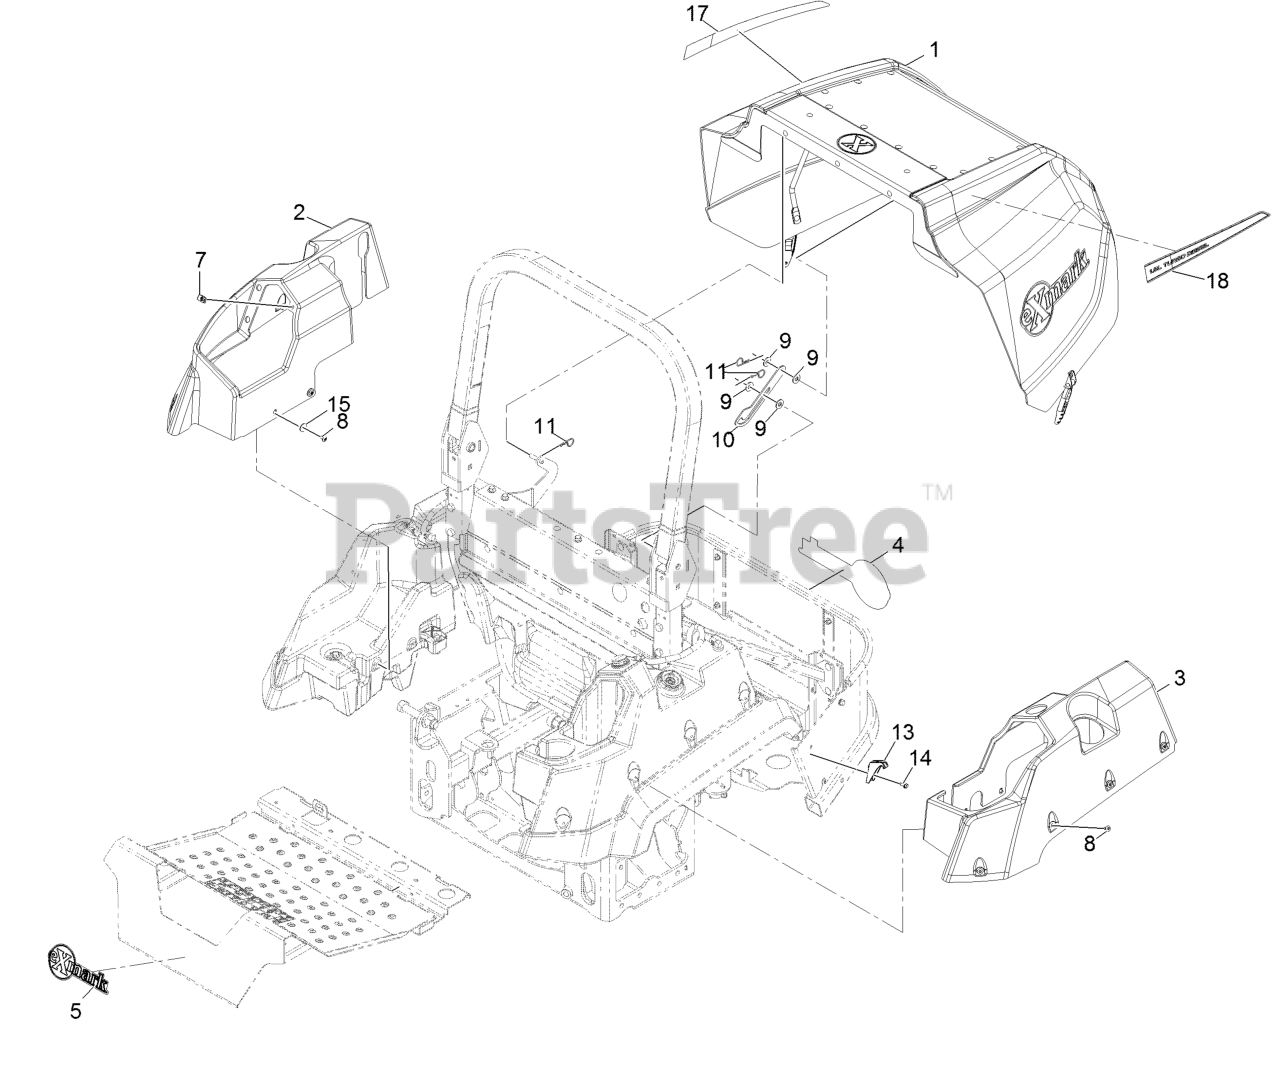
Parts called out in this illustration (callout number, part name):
1	Hood ASM
2	Cover-Tank, RH
3	Cover-Tank, LH
4	Decal-Exmark
5	Decal-Exmark
8	Screw-Torx
9	Washer-Flat
10	Prop-Hood
11	Pin-Cotter, Hair
13	Latch-Catch
14	Screw-HWH
15	Washer-Flat
17	Decal-Turbo Diesel-RH
18	Decal-Turbo Diesel-LH
